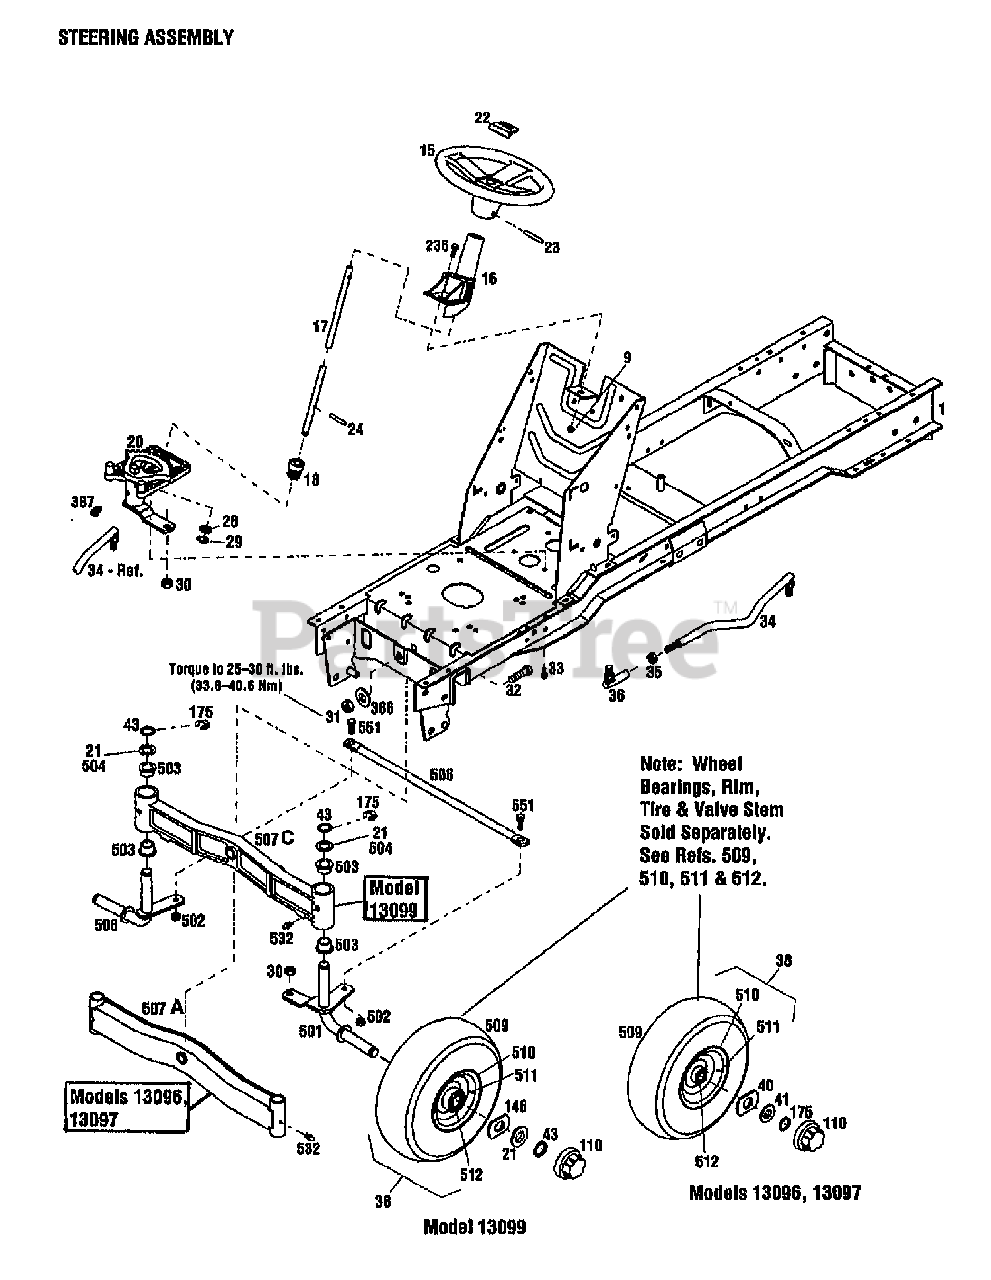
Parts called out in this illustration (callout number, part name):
1	ASSM-FRAME LTX {13096/097}
1	ASSM-FRAME {13099}
9	NUT-HFLK 5/16-18 ZP
15	WHEEL-STEERING
16	SUPPORT-STEERING SHAFT
17	SHAFT-STEERING
18	GEAR-PINION
20	ASSM-STEERING GEAR
21	WASHER-THRUST {13096,13097}
21	WASHER-THRUST {13099}
22	CAP-STEERING
23	PIN-ROLL .25X2.25
24	PIN-ROLL 1/4 X 1-1/4
28	WASHER-1.0X.64X.09
29	RING-RETAINING
30	NUT-HEX/JAM 1/2-20
31	NUT-H/LK 5/8-11
32	SCR-HH
33	SCR-HFLK 5/16-18X.75
34	LINK-DRAG
35	NUT-JAM
36	JOINT-BALL
38	ASSM-WHEEL & TIRE FRONT {13096,13097}
38	ASSM-WHEEL & TIRE FRONT {13099}
40	WASHER-SPEC .75X2.50
41	WASHER-1.38 X.765X .06 ZP
43	RING-HEAVY EXT HD 1.0 ID {13099}
110	CAP-HUB
146	WASHER-SPECIAL .75X2.5
175	RING-RET."E".577 ID
236	SCR-HFLK 5/16-18X.75 ZP
366	WASHER-1.75X.687X.134 ZP
387	FITTING-GREASE 90 DEGREE
501	ASSM-SPINDLE LH {13096/097}
501	SPINDLE-WHEEL LH {13099}
502	NUT-LOCK
503	BUSHING {13096/097}
503	BEARING-FLANGE {13099}
504	WASHER-1.25X.765X.049
506	KIT-TIE ROD W/HDW
507	AXLE-FRONT {13096/097}
507	AXLE-FRONT {13099}
508	ASSM-SPINDLE WHEEL RH {13096/097}
508	SPINDLE-WHEEL RH {13099}
509	TIRE 15X6.00-6RS {13096/097}
509	TIRE-16X6.50-8 {13099}
510	DISC WHEEL {13096/097}
510	RIM-WHEEL {13099}
511	STEM-VALVE
512	BEARINGS-WHEEL {13096/097}
512	BEARING-BALL {13099}
532	FITTING-GREASE 1/4-28X2.00
551	SCR-SHOULDER
